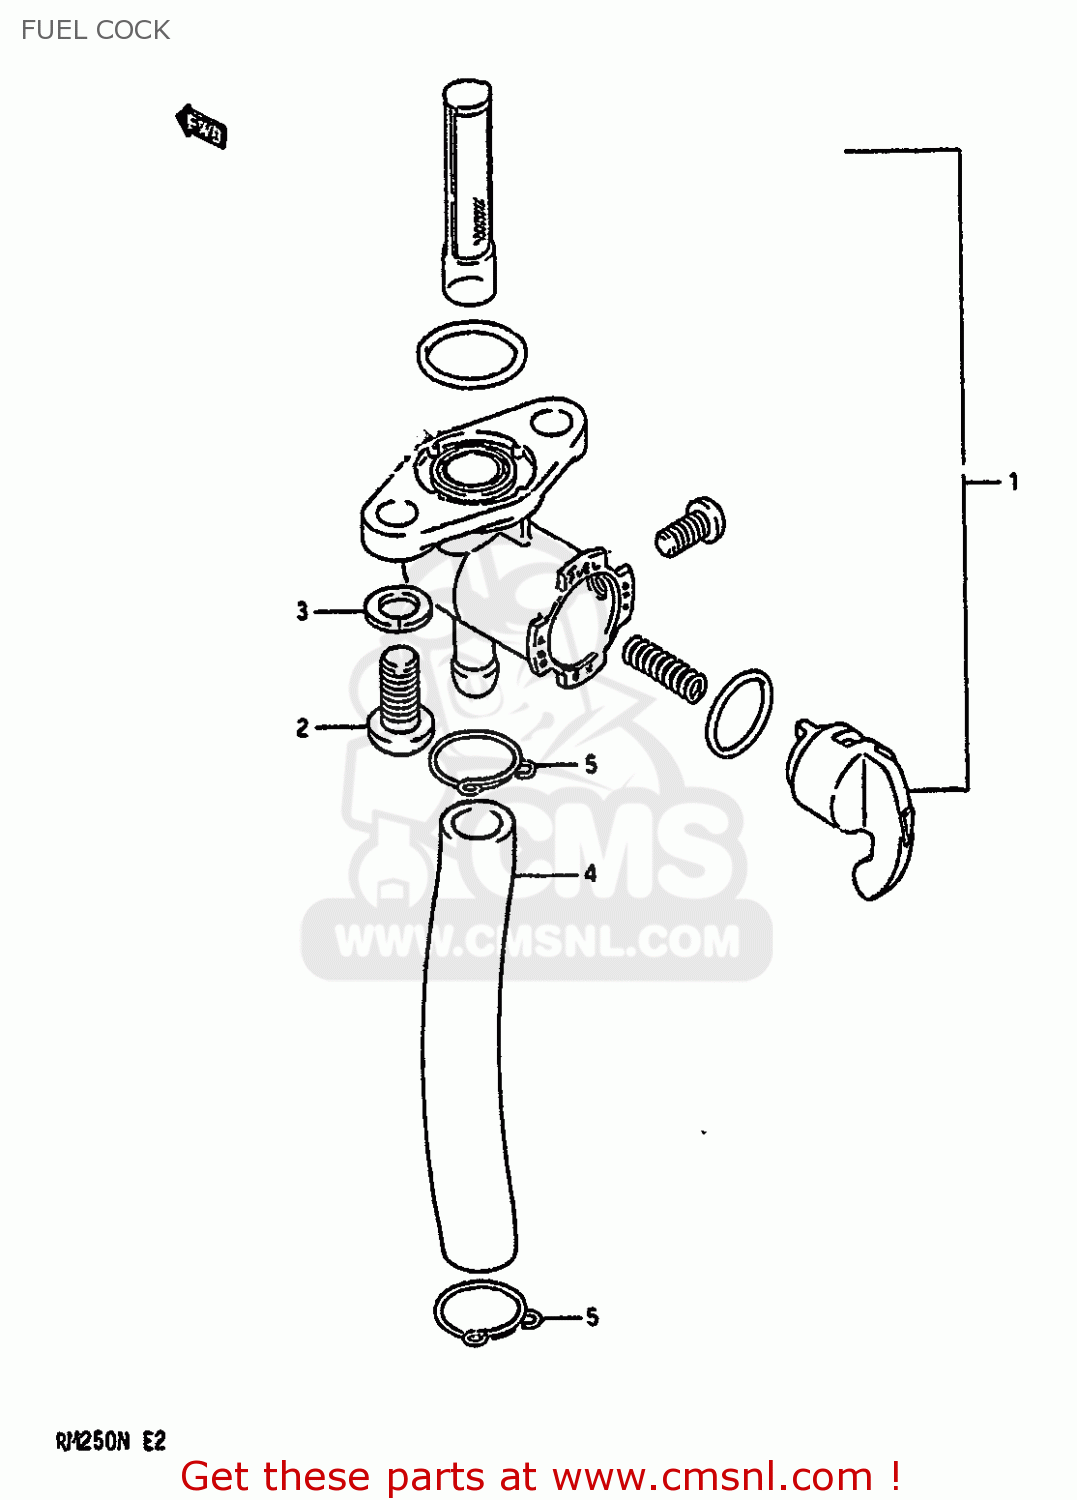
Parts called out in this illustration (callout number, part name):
1	COCK ASSEMBLY,FUEL
2	SCREW
3	WASHER,LOCK
4	HOSE (6.5X11.5X300)
5	CLIP
